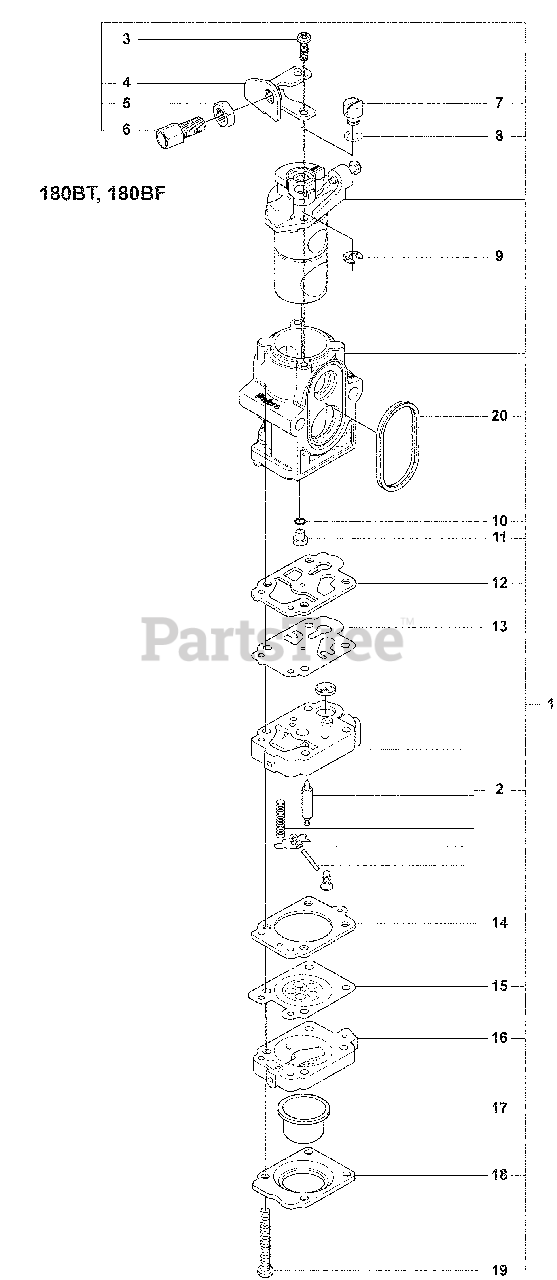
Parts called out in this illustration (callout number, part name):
1	Carburetor Assembly
2	Pump Body, A
3	Screw
5	Nut
6	Screw
7	Swivel
8	Washer
10	O-Ring
12	Gasket
13	Diaphragm
14	Gasket
15	Diaphragm
16	Diaphragm
17	Primer Blub
18	Cover
19	Screw
20	Ring
